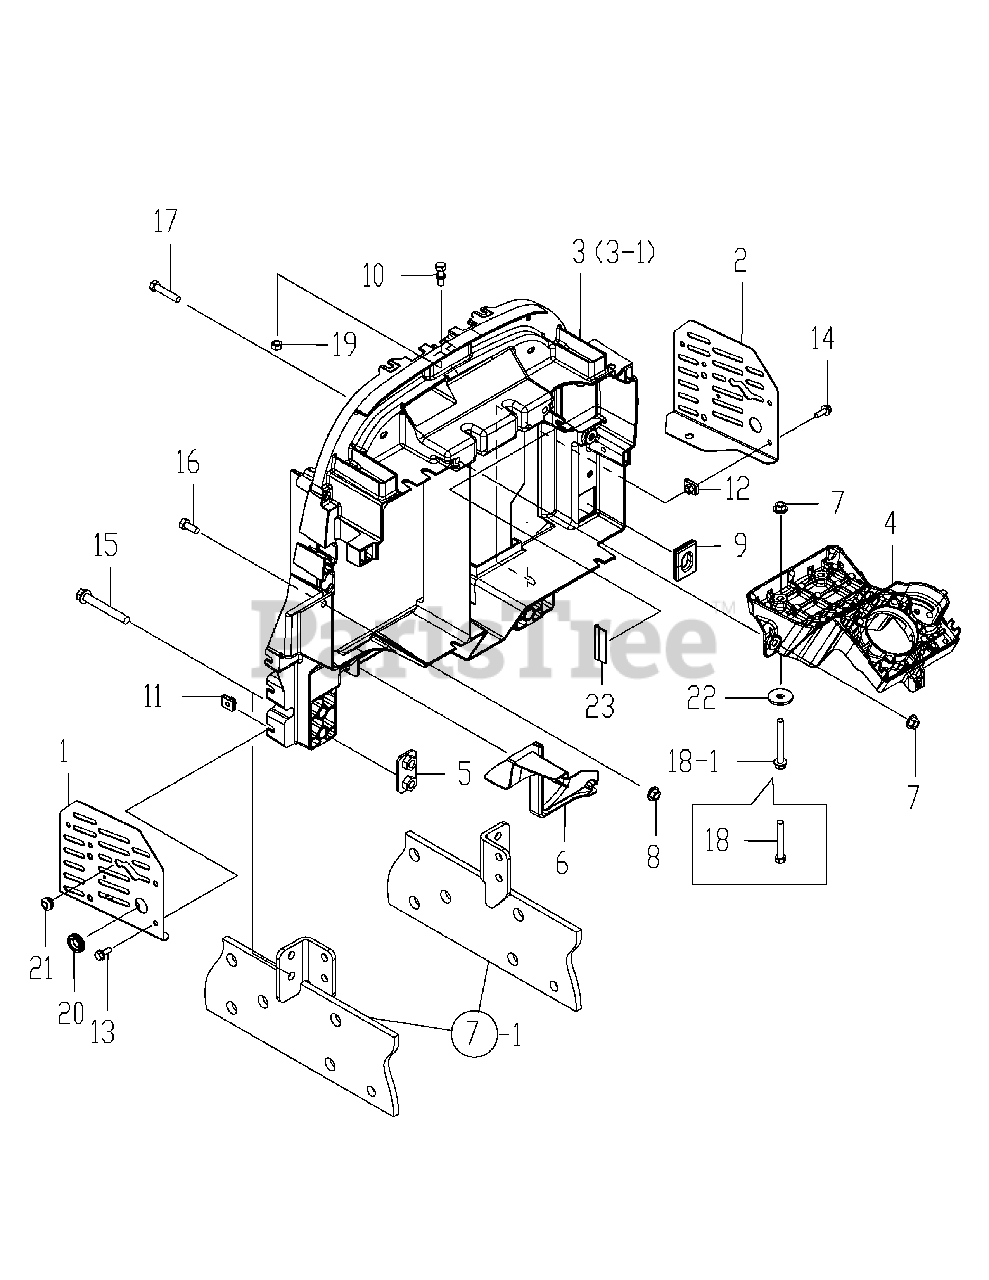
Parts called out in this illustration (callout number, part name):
1	COVER ASSY, LH, F-BELT
2	COVER RH, FAN BELT
3	BRACKET, COLUMN
3-1	BRACKET, COLUMN
4	BRACKET, STEERING
6	BOOT, DASHCOVER
9	GROMMET, HARNESS
18-1	BOLT, 8 X 65 PLATED
20	GROMMET, 16.0 X 2
22	WASHER, 9 X 32 X 3.2
23	SEAL , FENDER
